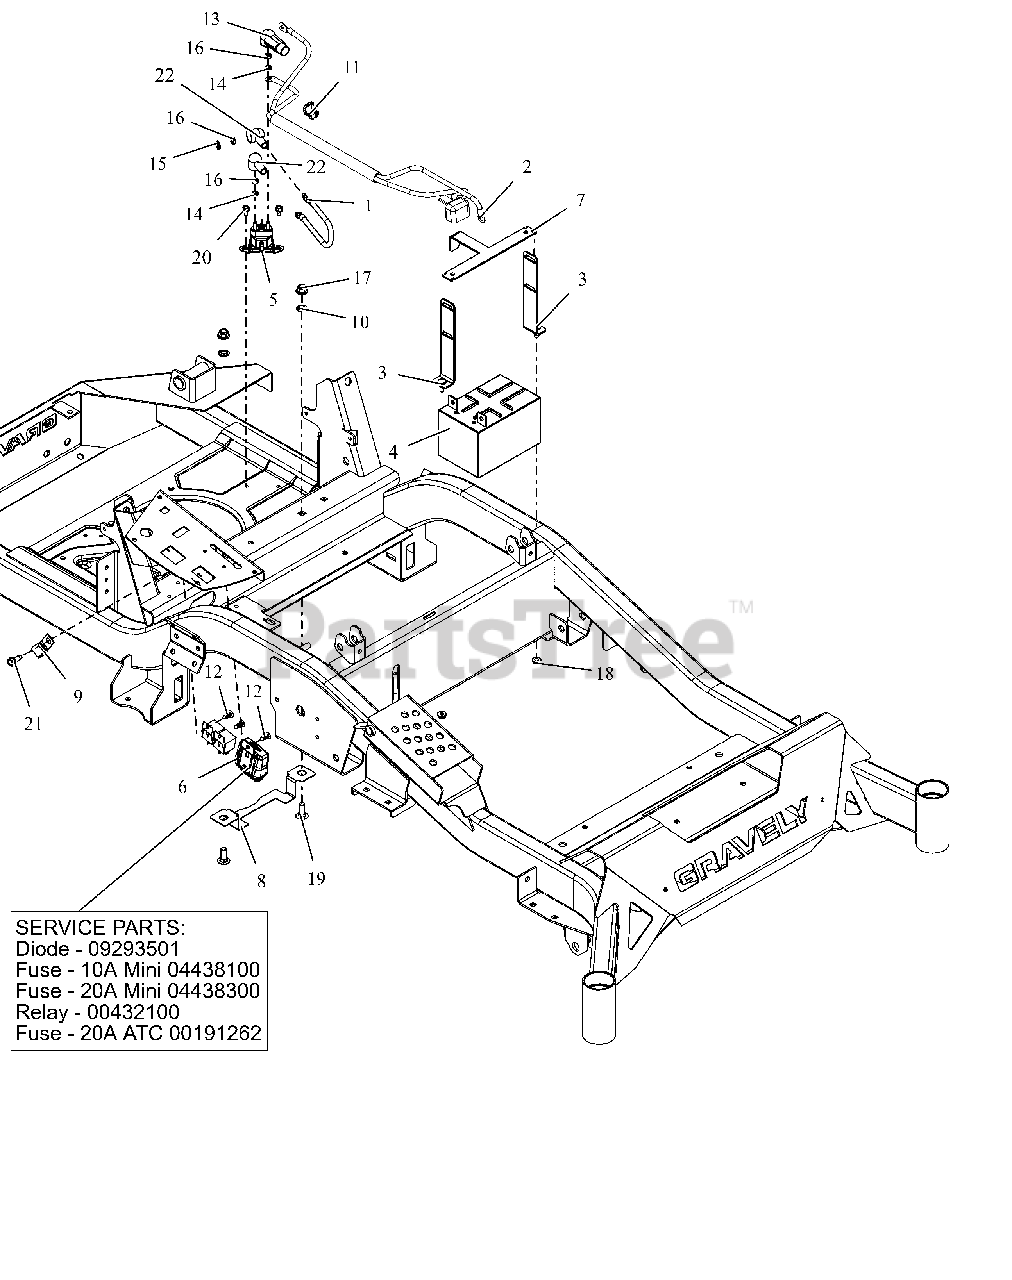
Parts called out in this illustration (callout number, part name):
1	CABLE, POS W/(2)1/4 RING 9.0LG
2	HARNESS, BATTERY HD
3	WMT,BATTERY MOUNT HOLD DOWN
4	BATTERY, 12V 12A-190CCA
5	SOLENOID, STARTER (SEALED)
6	HARNESS, WIRE
6	DIODE, CONNECTOR SHELL
6	FUSE,10 AMP MINI-ATC
6	FUSE,20 AMP MINI ATC
6	RELAY,SEALED W/DIODE
6	FUSE, 20 AMP BLADE S/O
7	BRKT, BATTERY TIE DOWN
8	GUARD, ELECTRICAL HARNESS
10	NUT-PUSH .38 DIA. PAL ZINC
11	CABLE TIE W/ TREE (.25 HOLE)
12	RIVET, .25 NYLON PANEL
13	BOOT, .65ID POS
14	WSHR,LK-EXT.262X.502X.026 ZCC
15	WSHR,LK-REG .312X.078 ZCC
16	NUT-STD M6-1.0 ZCC
17	NUT,NYL-FLG .38-16 GF ZCC
18	NUT-LK-TOP-FLG .250-20 GF ZCC
19	BLT, RHSN .38-16X1.00 G5 ZCC
20	SCR,TAP .25-20X.375 HWH TR ZCC
21	SCR,TAP .312-18X.75 HWH TR ZCC
22	BOOT, EYELET TERMINAL
